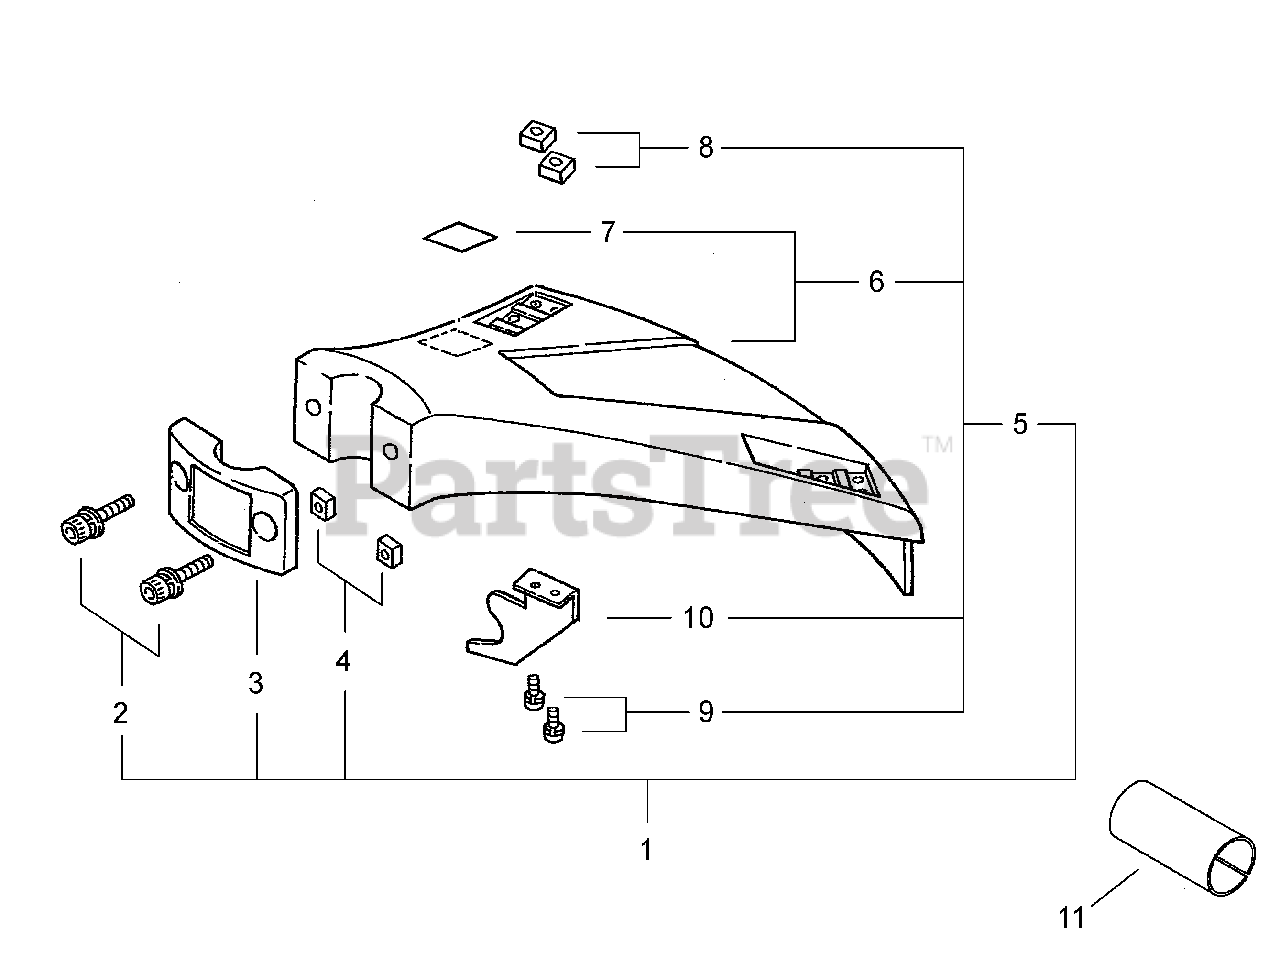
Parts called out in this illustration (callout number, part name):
1	DEBRIS SHIELD ASSY
2	SCREW - 5X25
3	CAP
4	NUT - 5
5	DEBRIS SHIELD KIT
6	SHIELD, DEBRIS
7	LABEL - CAUTION
8	NUT
9	SCREW - 4X16
10	CUTTER, LINE
